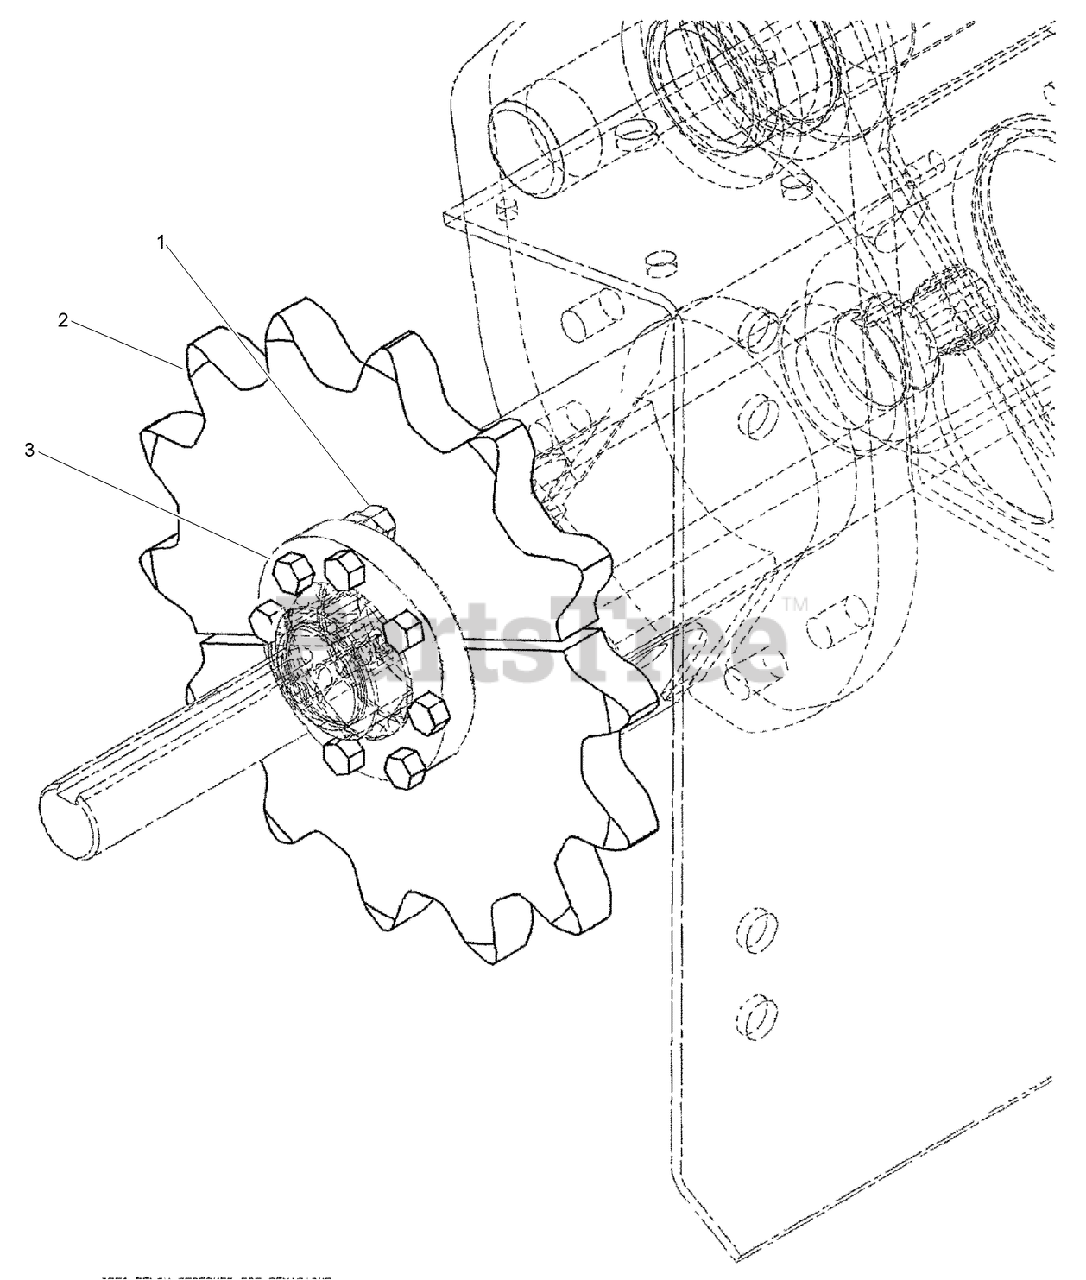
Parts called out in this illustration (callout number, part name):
1	NUT-LOCK
2	SPROCKET-Chainline Drive
3	SCREW-HH
